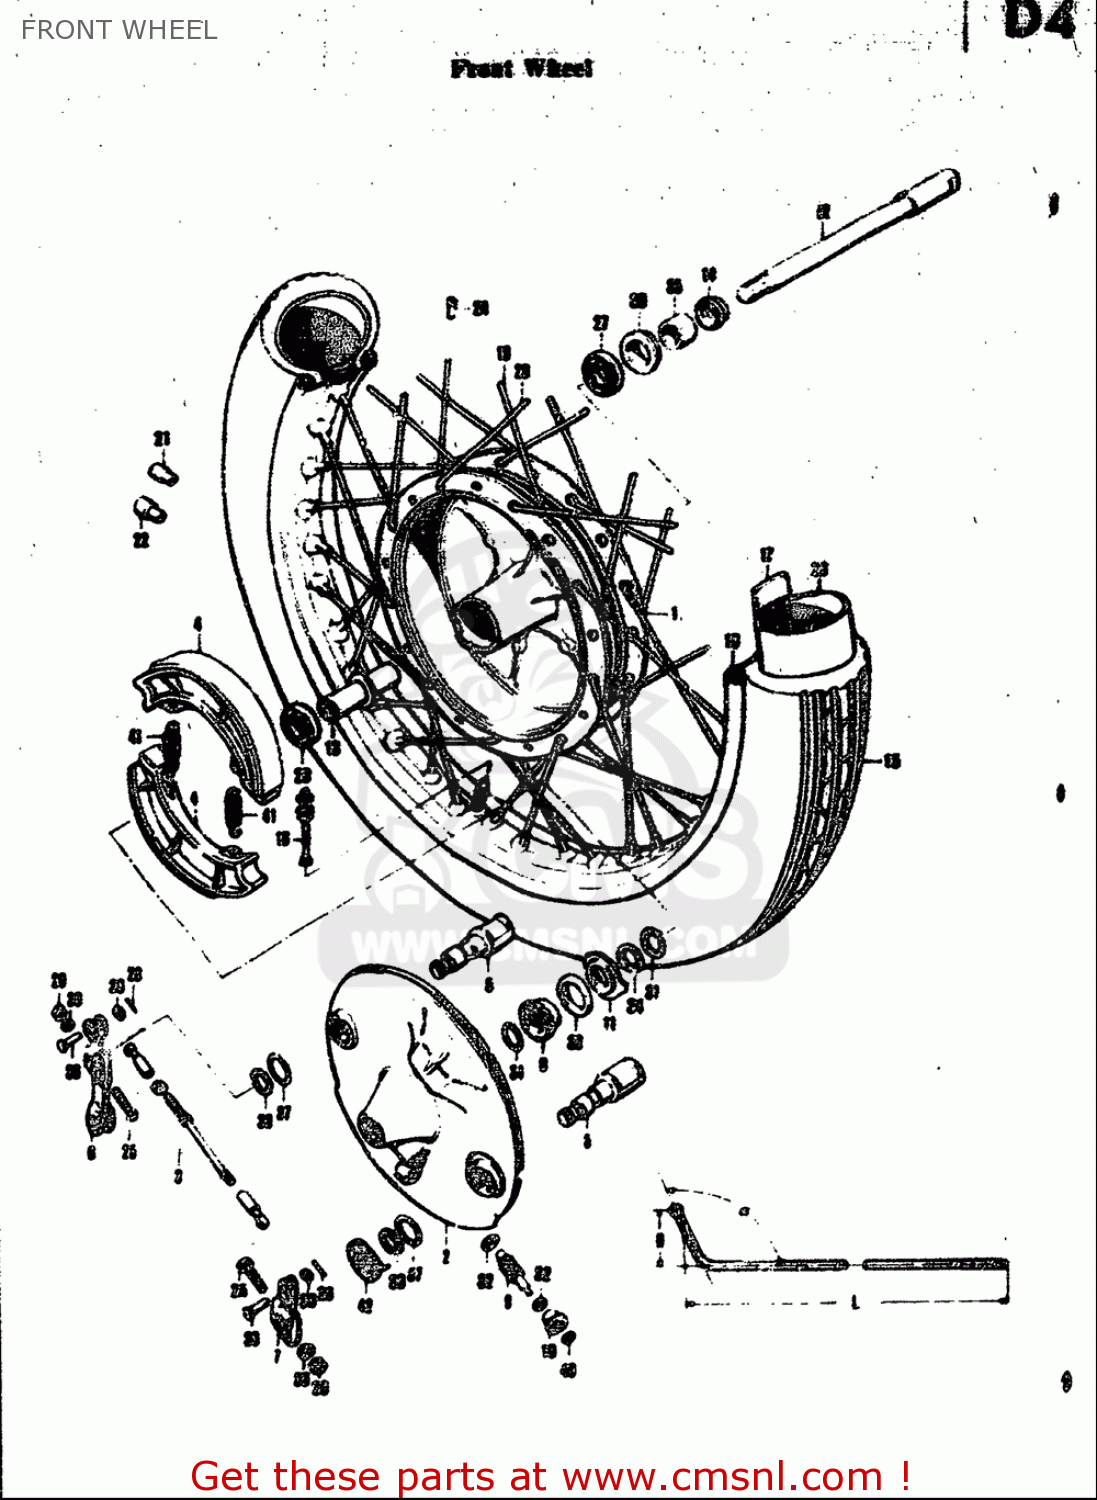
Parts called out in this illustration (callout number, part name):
9	PINION,SPEEDOMETER
10	BUSHING,SPEEDOMETER PINION
11	DRIVER,SPEEDOMETER GEAR
12	AXLE,FRONT
13	SPACER,FRONT HUB BEARING
17	PROTECTOR,INNER TUBE
21	BALANCER,WHEEL (B)
22	BALANCER,WHEEL (30G)
26	PIN 12X10
27	BEARING
28	BEARING
29	NUT
30	WASHER
31	CIRCLIP
32	WASHER(5.1X9X0.4)
33	WASHER(15.5X24X1.6)
34	WASHER(22.5X27X1)
35	SPACER
37	O RING(D:2.4,ID:14.8)
39	SEAL,OIL(26X38X4)
40	SEAL,OIL(6X10X3)
42	SPRING
